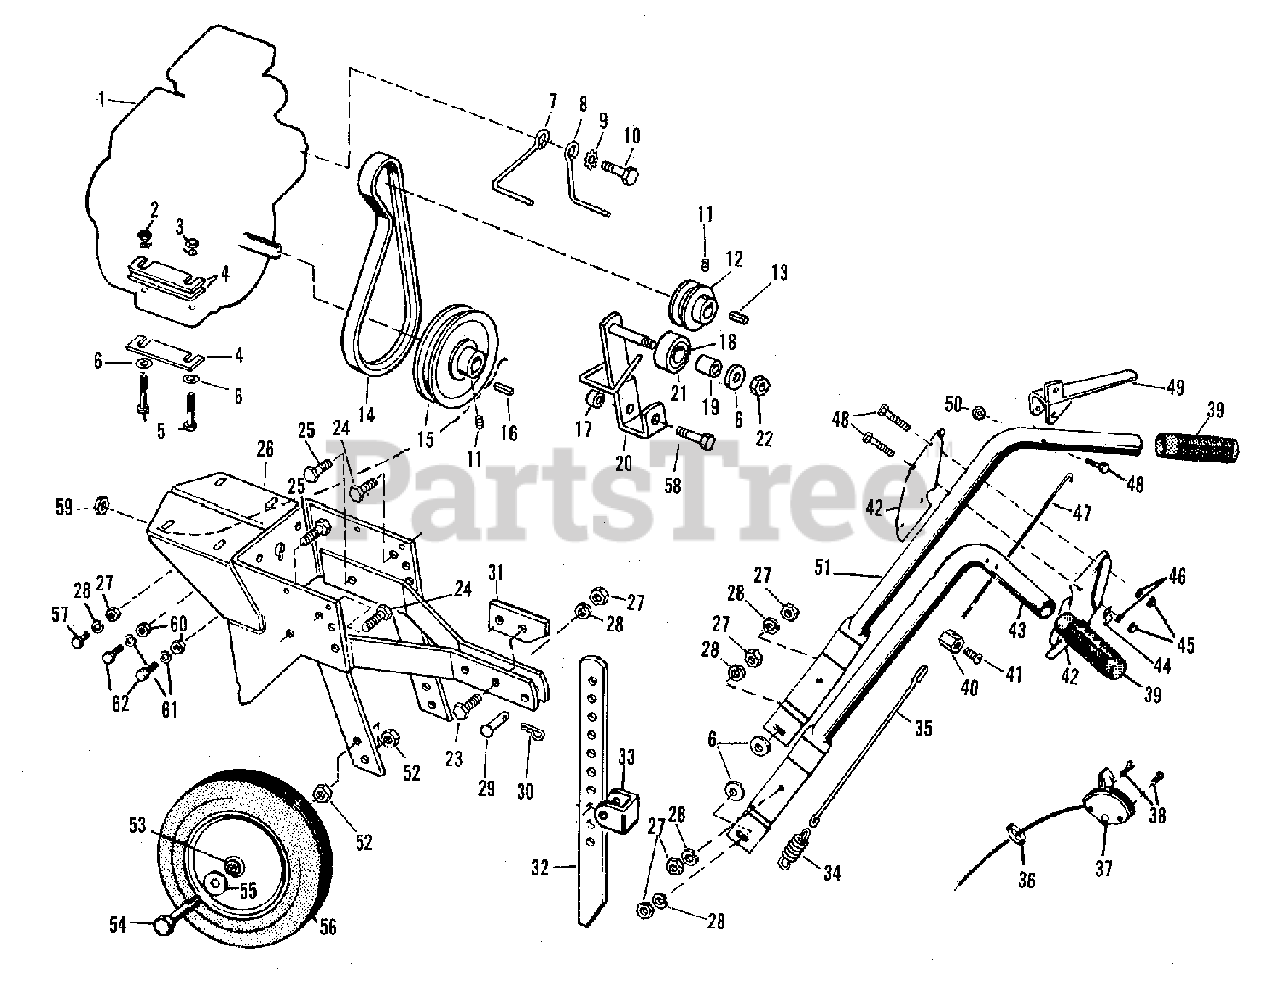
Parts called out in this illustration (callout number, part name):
1	ENGINE, 3 H.P.
2	NUT, Hex, 5/16-18
3	WASHER, Lock, 5/16"
4	SHIM, Engine
5	SCREW, Hex, Cap, 5/16-18 x 2
6	WASHER, Flat, 5/16
9	WASHER, Lock 1/2
10	SCREW, Hex Cap, 1/2-20 x 1
11	SCREW, Set, 5/16-18 x 5/16
12	PULLEY, Engine
15	PULLEY, Driven
19	LEVER, Idler
20	PULLEY, Idler
22	NUT, Hex Lock, 3/8-16
23	SCREW, Hex Cap, 3/8-16 x 1-1/2
24	SCREW, Hex Cap, 3/8-16 x 7/8
25	SCREW, Hex Cap, 3/8-16 x 1-1/4
27	NUT, Hex, 3/8-16
28	WASHER, Lock, 3/8"
30	CLIP, Spring
35	WIRE, Extension
37	CONTROL, Throttle
38	SCREW, Self Tapping, 10-24 x 1
39	GRIP, Handle
41	SCREW, Round, 10-24 x 3/8
42	COVER, Handle, (Upper)
43	HANDLE, L.H.
44	CLAMP, Cable
45	NUT, Hex, 1/4-20
46	WASHER, Lock, 1/4
47	SPRING, Extension
48	SCREW, Hex Cap, 1/4-20 x 1-1/2
49	GRIP, Clutch
50	NUT, Hex, Lock, 1/4-20
51	HANDLE, R.H.
52	NUT, Hex, 1/2-13
53	SCREW, Hex, Cap, 1/2-13 x 3
54	WASHER, Flat, 1/2
55	WHEEL & TIRE
56	BUSHING, Wheel
57	SCREW, Hex, Cap, 3/8-16 x 3/4
59	NUT, Special, 5/16-18
60	NUT, Hex, 7/16-20
61	WASHER, Lock, 7/16"
62	SCREW, Hex, Cap, 7/16-20 x 1-1/4
